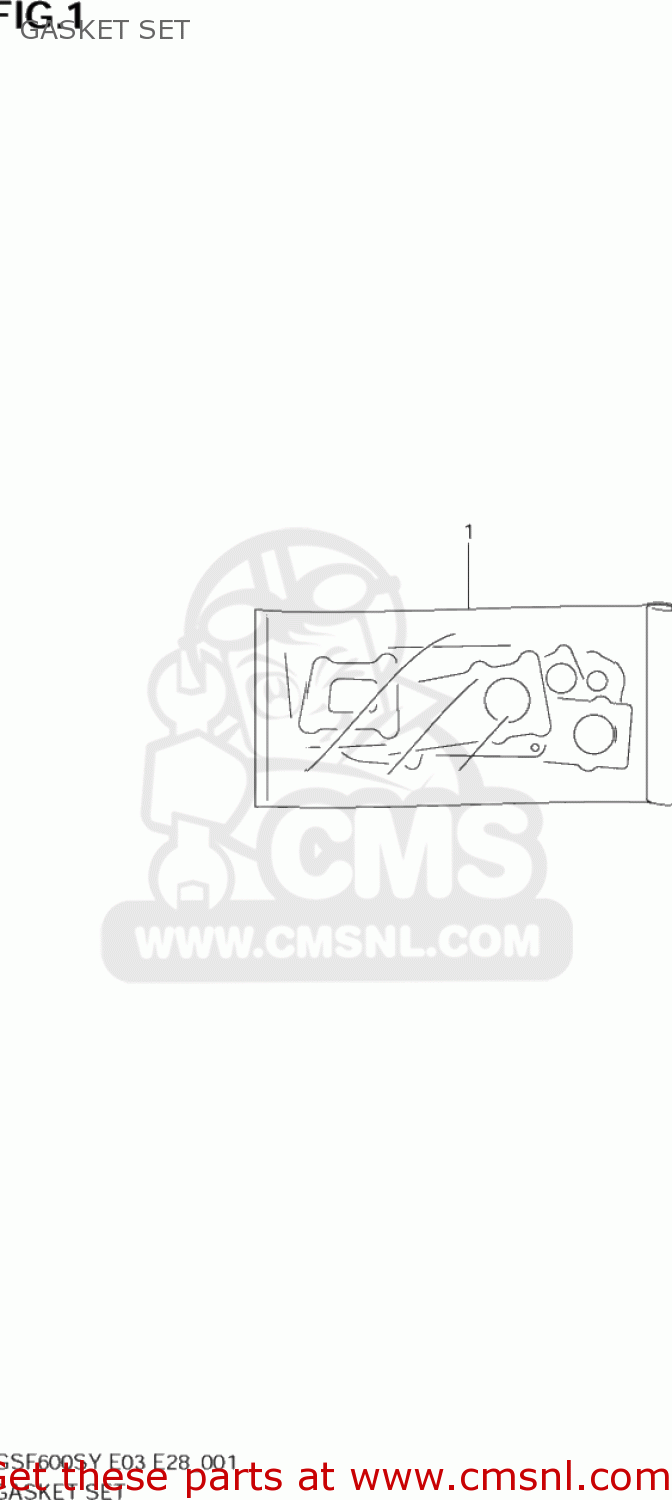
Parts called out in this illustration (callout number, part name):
1	PAKKING SET (NAS)
2	GASKET,CYLINDER HEAD (NAS)
3	GASKET,CYLINDER HEAD COVER (NAS)
4	GASKET,BREATHER COVER
5	GASKET,HEAD COVER NO.2 (NAS)
6	GASKET,HEAD COVER NO.3 (NAS)
7	GASKET,CYLINDER (NAS)
8	GASKET,CL COVER (NAS)
9	GASKET,STARTER GEAR COVER (NAS)
10	GASKET,OIL PAN(ASB) (NAS)
11	GASKET,SIGNAL GEN COVER (NAS)
12	GASKET,TENSIONER ADJUSTER (NAS)
13	GASKET,EXHAUST (NAS)
14	O RING,OIL PUMP
15	GASKET,OIL STRAINER PROTECTOR (NAS)
16	GASKET,OIL OUTLET (NAS)
17	GASKET,2ND AIR PIPE (NAS)
18	WASHER(10.6X25.5X2.3)
19	GASKET(5.8X11X1.2) (NAS)
20	GASKET 8.2X14X1 (NAS)
21	GASKET(8.5X17X2.3) (NAS)
22	GASKET(10.2X20X2).3 (NAS)
23	GASKET(12.1X16.2X3.7) (NAS)
24	GASKET(13.8X18.8X4.8) (NAS)
25	GASKET(16X22X2) (NAS)
26	O RING(D:1.2,ID:4)
27	O RING(D:2.4,ID:12.3)
28	O RING(D:2.6,ID:12.1)
29	O RING(D:2.5,ID:13.8)
30	O RING(D:2.4,ID:15.8)
31	O RING(D:2.4,ID:16.8)
32	O RING(D:3.1,ID:16.8)
33	O RING(D:3.2,ID:17.8)
34	O RING(D:2.5,ID:21)
35	O RING(D:3.7,ID:21.7)
36	O RING(D:2.4,ID:39.7)
